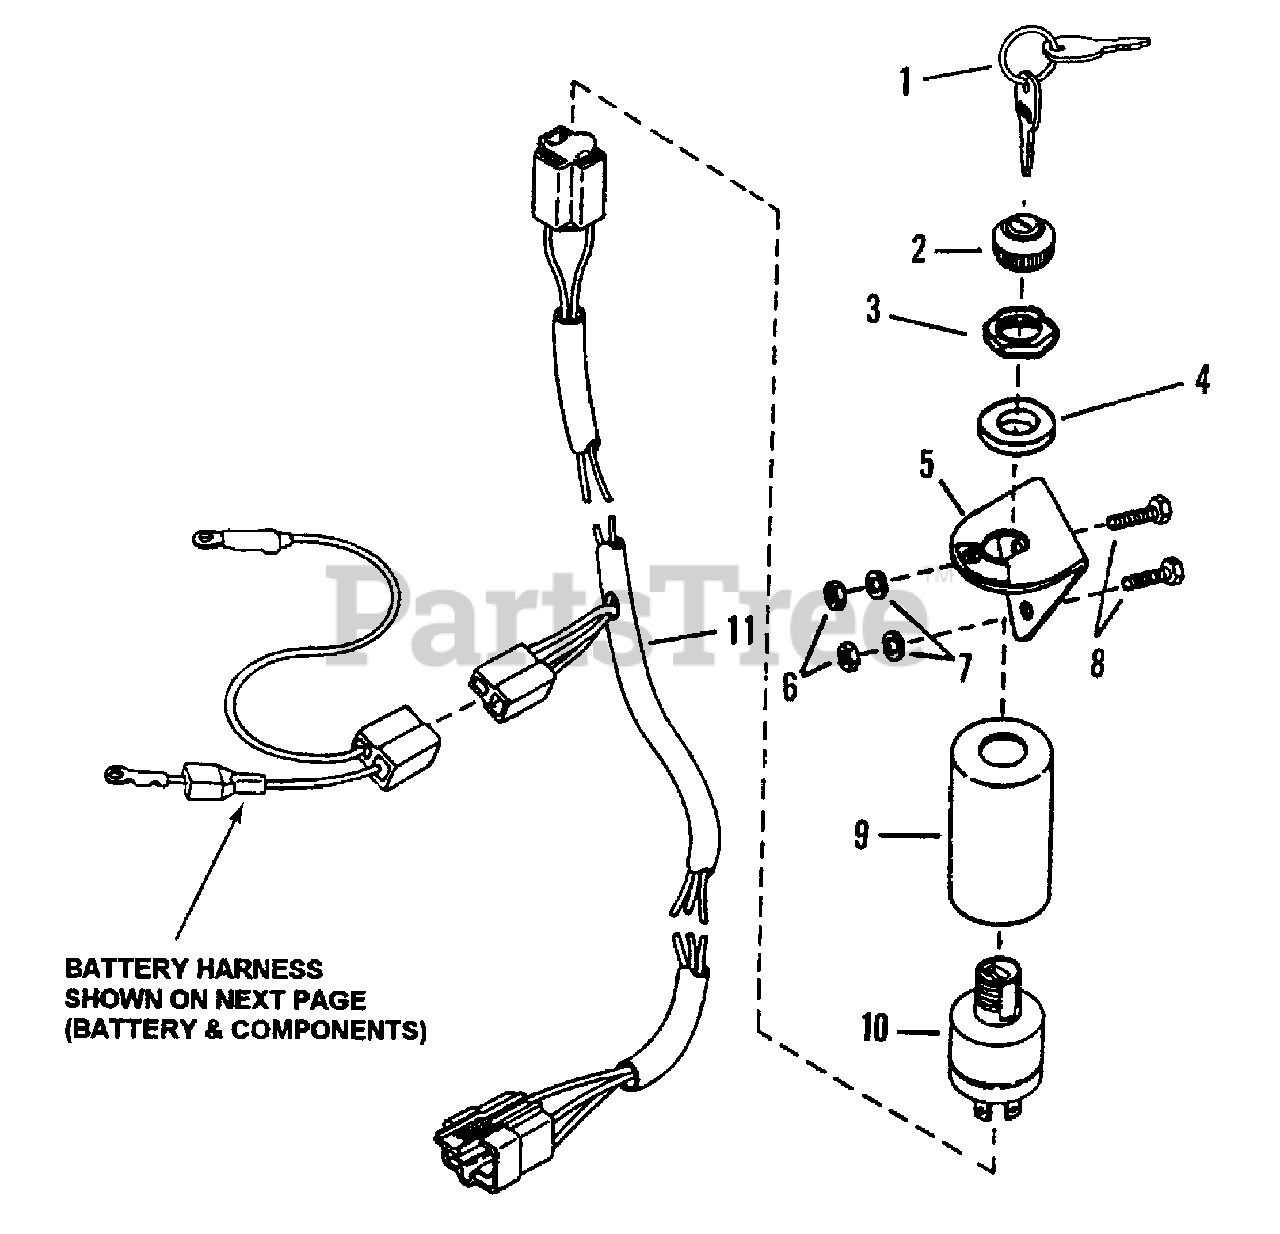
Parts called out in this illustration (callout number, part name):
1	KEY (Set of Two)
2	BEZEL
3	NUT, 3/4-20 Hex Lock
4	SPACER
5	BRACKET, Ignition Switch
6	NUT, 14-28 Hex
7	WASHER, 1/4" Internal Tooth Lock
8	SCREW, 1/4-28 X 1-3/8" Hex Head Cap
9	COVER, Switch
10	SWITCH, Ignition
11	HARNESS, Wiring
